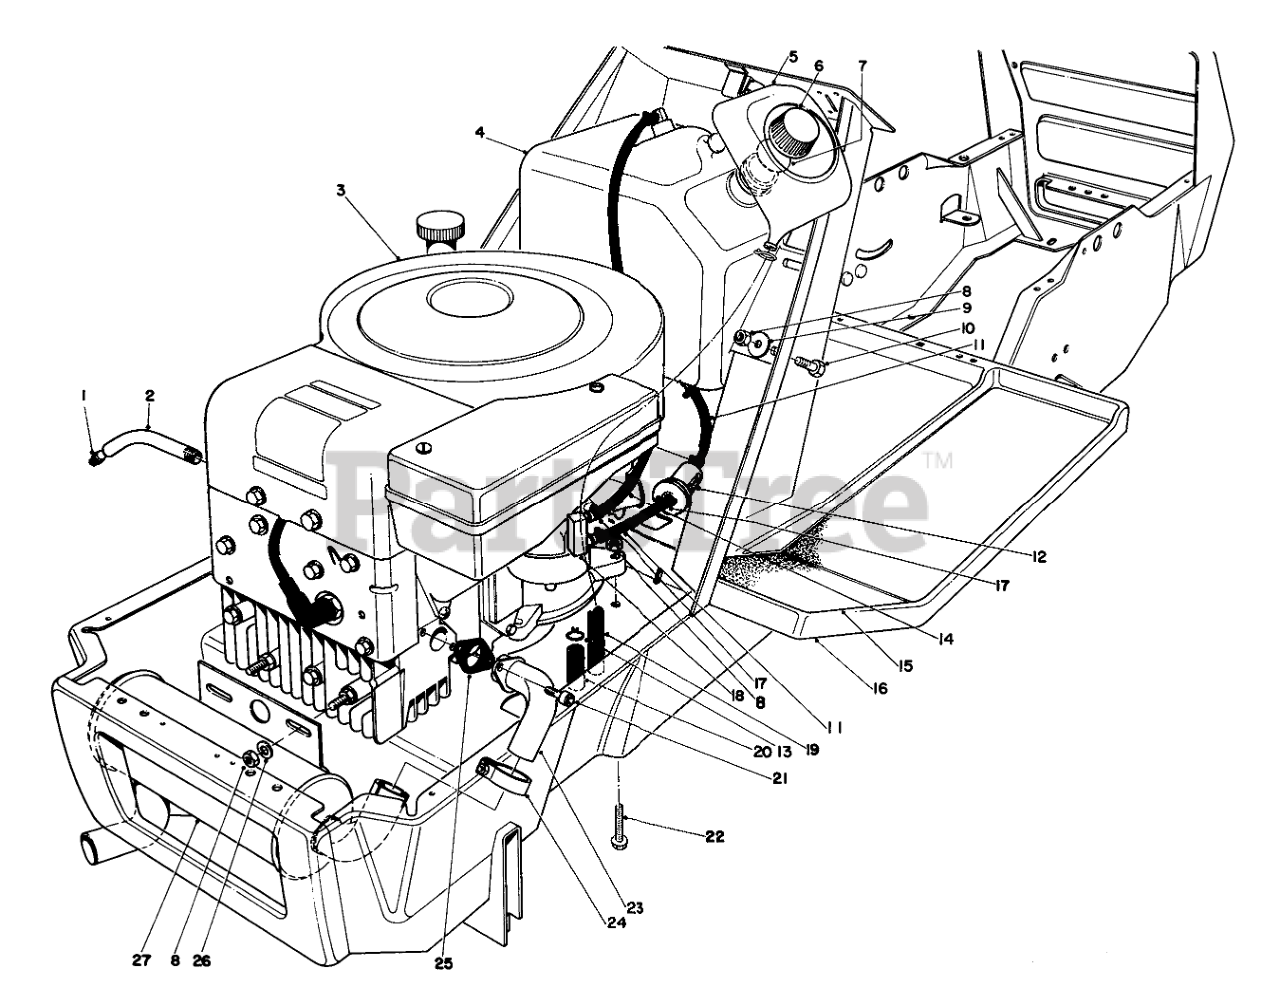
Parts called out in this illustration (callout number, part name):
1	PLUG-PIPE, SQH
2	OIL DRAIN TUBE
3	Engine
4	Gas Tank (Incl. Ref. #5)
5	Funnel Overflow
6	Gas Cap Assembly (Incl. Ref. #7)
7	Gasket Gas Cap
8	NUT-LOCK, CONE
9	WASHER
10	SCREW-HH
11	GAS HOSE
12	Fuel Filter
13	HOSE CLAMP
14	Gas Return Hose
15	LH FOOT TREAD
16	Frame
17	CLAMP-HOSE
18	Fitting Carburetor
19	FUNNEL HOSE
20	CARB DRAIN HOSE
21	SCREW-HSH
22	SCREW-HH
23	10 HP EXHAUST PIPE WA
24	MUFFLER CLAMP
25	Gasket Exhaust
26	WASHER-PLAIN
27	EXHAUST MUFFLER 10 HP
